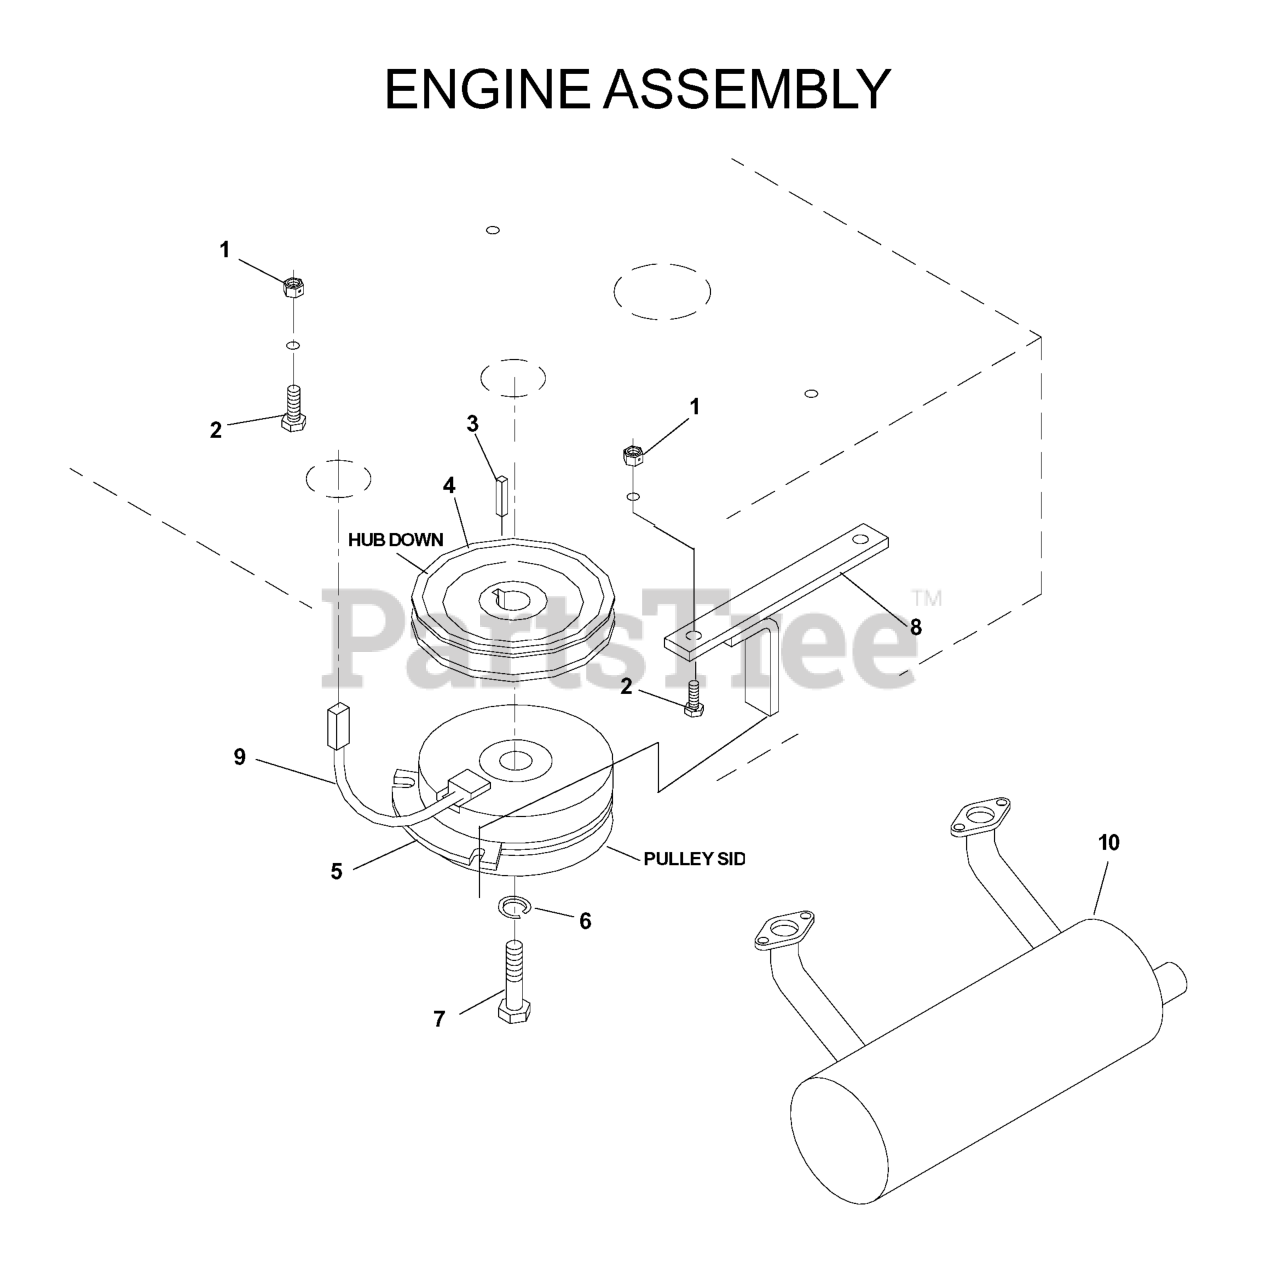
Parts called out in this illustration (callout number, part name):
1	NUT 5/16 NYLOC
2	HCS 5/16C X 1 3/4
3	KEY, 1/4 SQ X 1 1/4
5	CLUTCH-200 FT LB(RPLS 5218-102
6	WASHER 7/16 LOCK
7	BOLT 7/16F X 2 1/2
8	CLUTCH TIE DOWN
9	CLUTCH HARNESS
10	MUFFLER KAWASAKI GEN II
